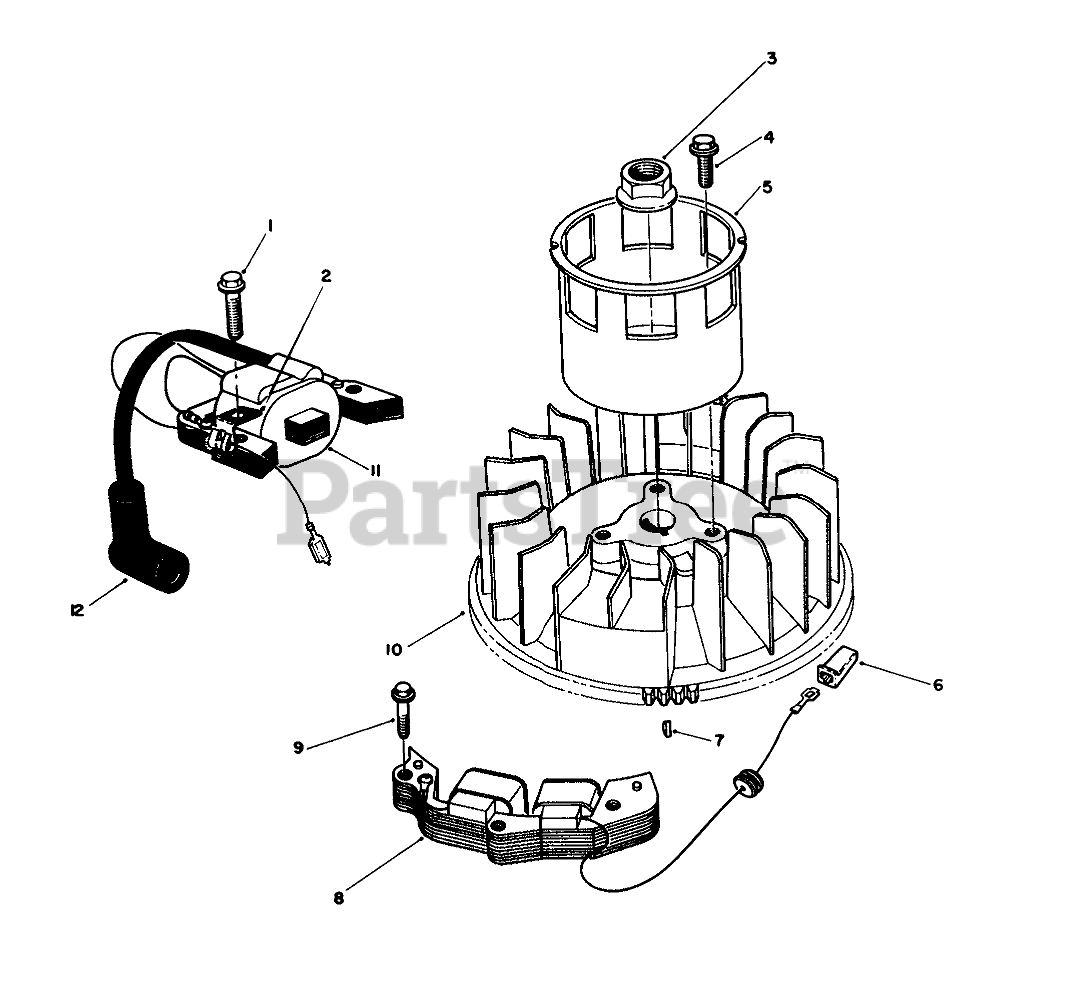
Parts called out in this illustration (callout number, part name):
2	CLAMP
6	CONNECTOR BODY
10	FLYWHEEL
11	COIL
12	COVER
